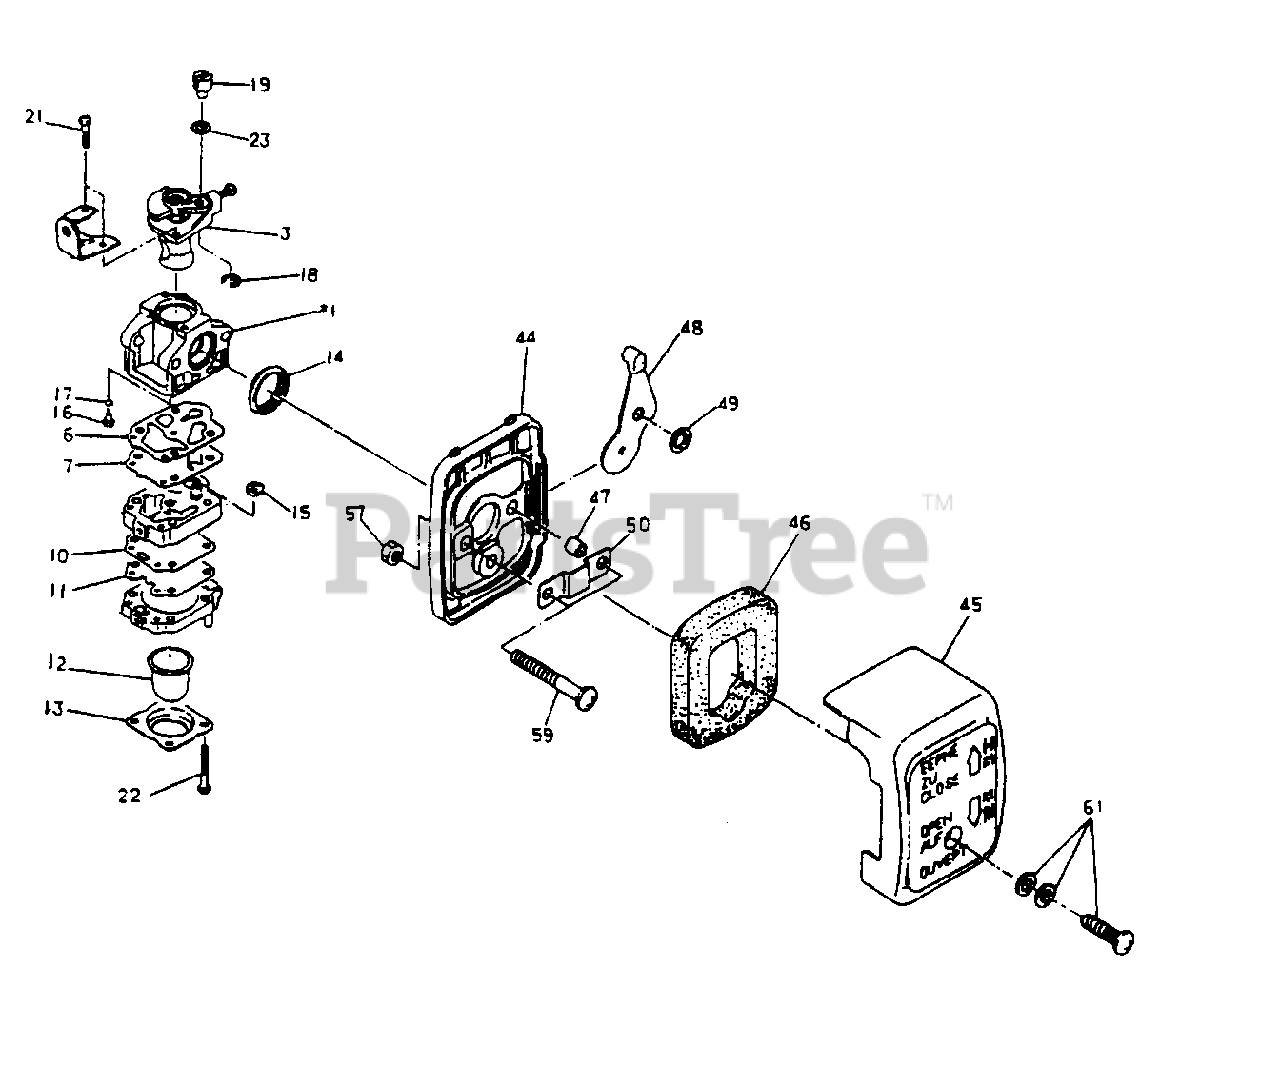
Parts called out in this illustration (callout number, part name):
1	Carburetor, Complete
5	Major Repair Kit (Inc. 6,7,10-17)
12	Pump, Primer
13	Cover, Primer Pump
20	Swivel Kit (Incl. 18. 19 & 23)
43	Air Cleaner Kit (Incl. 44-50, 57, 59 & 61)
46	Element, Air Cleaner
48	Lever, Choke
59	Screw Assembly
61	Screw Assembly
